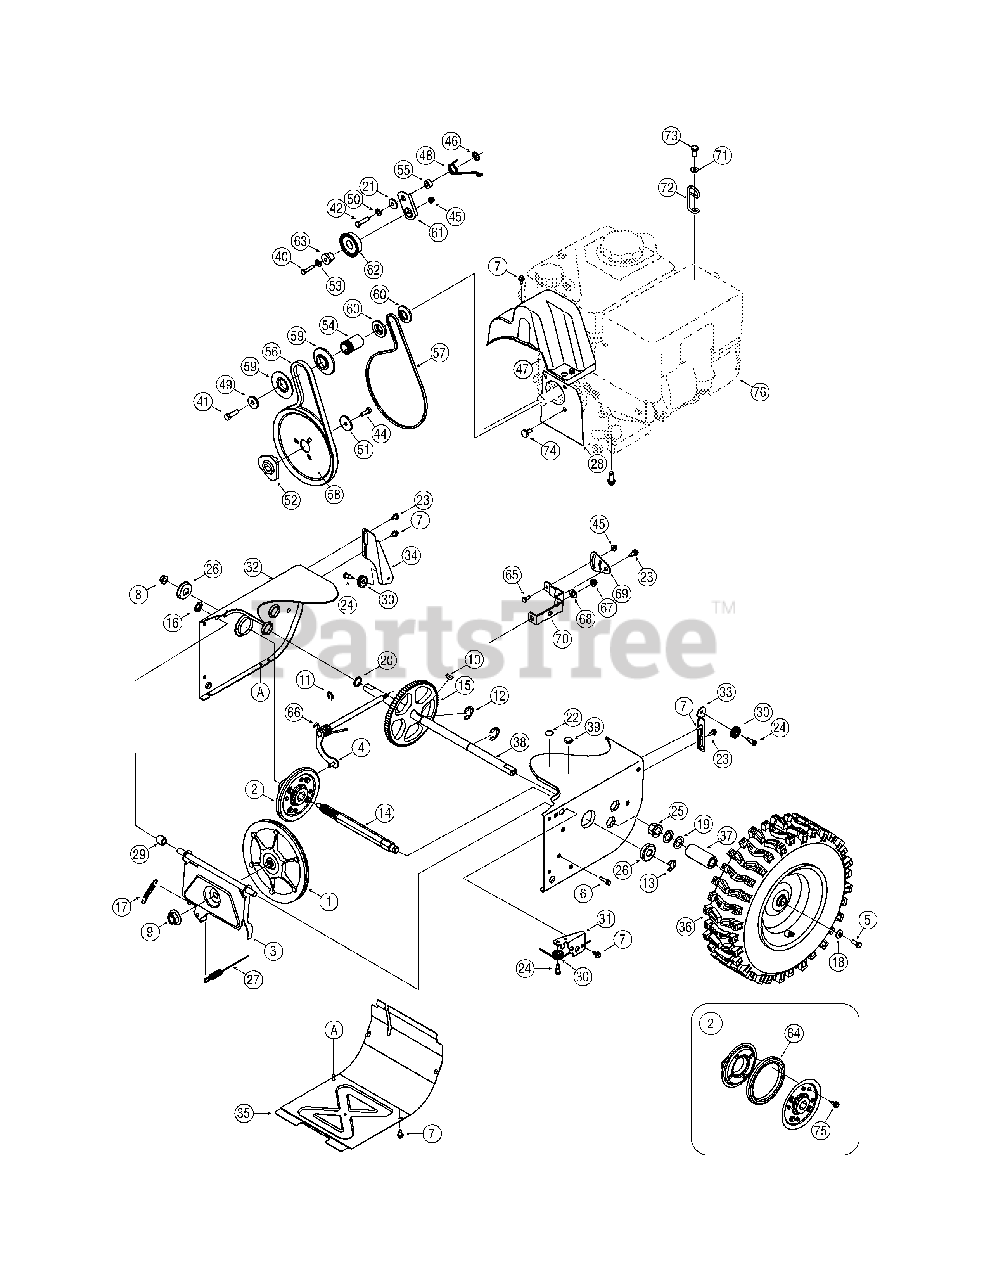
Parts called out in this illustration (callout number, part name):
1	Disc Assembly, Friction Wheel
2	Friction Wheel Assembly, 5.5 OD
3	Support Bracket, Friction Wheel
4	Shift Assembly, Rod
5	Hex Screw, 5/16-24, .750, Gr5
6	Screw, 1/4-20, 1.000
7	Screw, 1/4-20 x .625
8	Nut, Flange Lock, 3/8-16, Nylon
9	Nut, Jam Lock, 5/8-18, Gr5, Nylon
10	Key, Hi Pro, 3/16 x 3/4 Dia.
11	E-ring, .500 Dia.
12	E-ring, Retaining, .875 Dia.
13	E-ring, .750 Dia.
14	Hex Shaft, .8125, 7-Tooth
15	Gear, 80-Tooth
16	Speed Nut, .500
17	Extension Spring
18	Washer, Bell, .340 x .872 x .060
19	Washer, Flat, .793 x 1.24 x .060
20	Washer, Flat, .75 x 1.00 x .060
21	Spacer, Shldr., .3175 ID x .500 x .094
22	Plug, 1/2 ID
23	Screw, Shoulder, .37 x .105, 1/4-20
24	Screw, 1/4-28, .375
25	Bearing, Hex Flange x .75 ID
26	Bearing, Ball, 17 x 40 x 12
27	Clutch Cable, Wheel, 44.95"
28	Plate, Cover
29	Spacer, .508 ID x .75 OD x .68
30	Roller, Cable
31	Front Guide Bracket, Auger Cable
32	Frame
33	Guide Bracket, Auger Cable
34	Guide Bracket, Drive Cable
35	Cover, Frame
36	Wheel Assembly - RH
36	Wheel Assembly - LH
37	Spacer, 1.25 x .75 x 3.0
38	Axle, .75 x 22"
39	Plug, 3/8 ID
40	Hex Screw, 1/4-20, 1.25, Gr5
41	Hex Screw, 3/8-24, 1.25, Gr8
42	Hex Screw, 5/16-24, 1.25, Gr5
43	Screw, Sems, 3/8-16, 1.00
44	Hex Screw, 5/16-24, .875, Gr8
45	Nut, Flange Lock, 1/4-20, Nylon
46	Nut, Push-on, .25 Dia.
47	Cover, Belt
48	Spring, Torsion, .850 ID x .354
49	Washer, Flat, .406 x 1.25 x .157
50	Washer, Lock .3125
51	Washer, Flat, .34 x 1.50 x .150
52	Pulley, Adapter, .75 Dia.
53	Lock Washer
54	Spacer, .875 ID x 1.185 OD
55	Spacer, .340 x .750 x .360
56	Belt, Auger Drive
57	Belt, Wheel Drive
58	Pulley, Auger Drive, 8.1 x .5
59	Pulley, Half, V x 2.600 OD
60	Pulley, Half, 3/8-V x 1.7160 OD
61	Idler Bracket, Wheel Drive
62	Idler Pulley Assembly
63	Spacer, Shoulder, .26 x .79 x .538
64	Rubber, Friction Wheel, 5.5 OD
65	Hex Screw, 1/4-20, .620, Gr5
66	Spring, Torsion, .750 ID x .968
67	Nut, Flange Lock, 5/16-18, Nylon
68	Washer, Flat, .469 x .875 x .105
69	Pivot Bracket, Speed Selector
70	Shift Bracket, Speed Selector
71	Washer, Flat, .330 x .630 x .0635
72	Cable Control Wire
73	Screw, M8-1.25
74	Shoulder Screw
75	Screw, AB, 1/4-14 x .625
